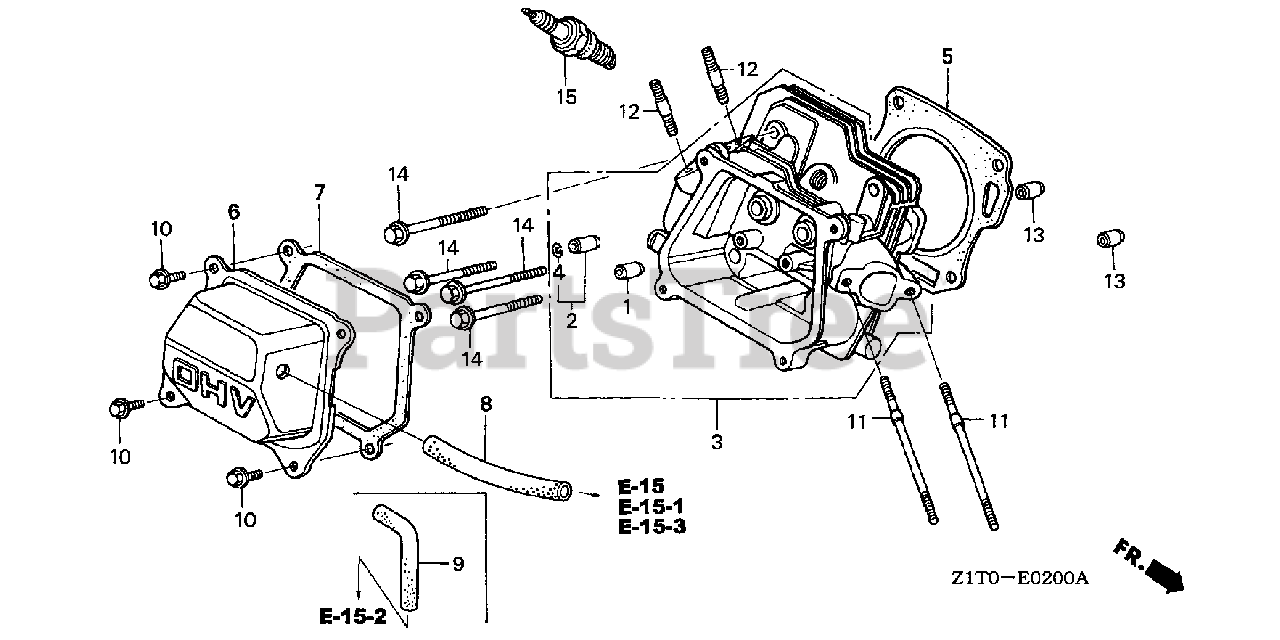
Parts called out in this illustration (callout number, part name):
1	GUIDE, VALVE (OVER SIZE)
2	GUIDE, EX. VALVE (OVER SIZE)
3	CYLINDER HEAD
4	CLIP, VALVE GUIDE
5	GASKET, CYLINDER HEAD
6	COVER, HEAD
7	GASKET, HEAD COVER
8	TUBE, BREATHER
10	BOLT, FLANGE (6X12) (CT200)
11	BOLT, STUD (6X112)
12	BOLT, STUD (8X32)
13	PIN, DOWEL (10X16)
14	BOLT, FLANGE (8X60)
15	SPARK PLUG (BPR5ES) (NGK)
15	SPARK PLUG (W16EPR-U) (DENSO)
15	SPARK PLUG (BPR6ES) (NGK)
15	SPARK PLUG (W20EPR-U) (DENSO)
